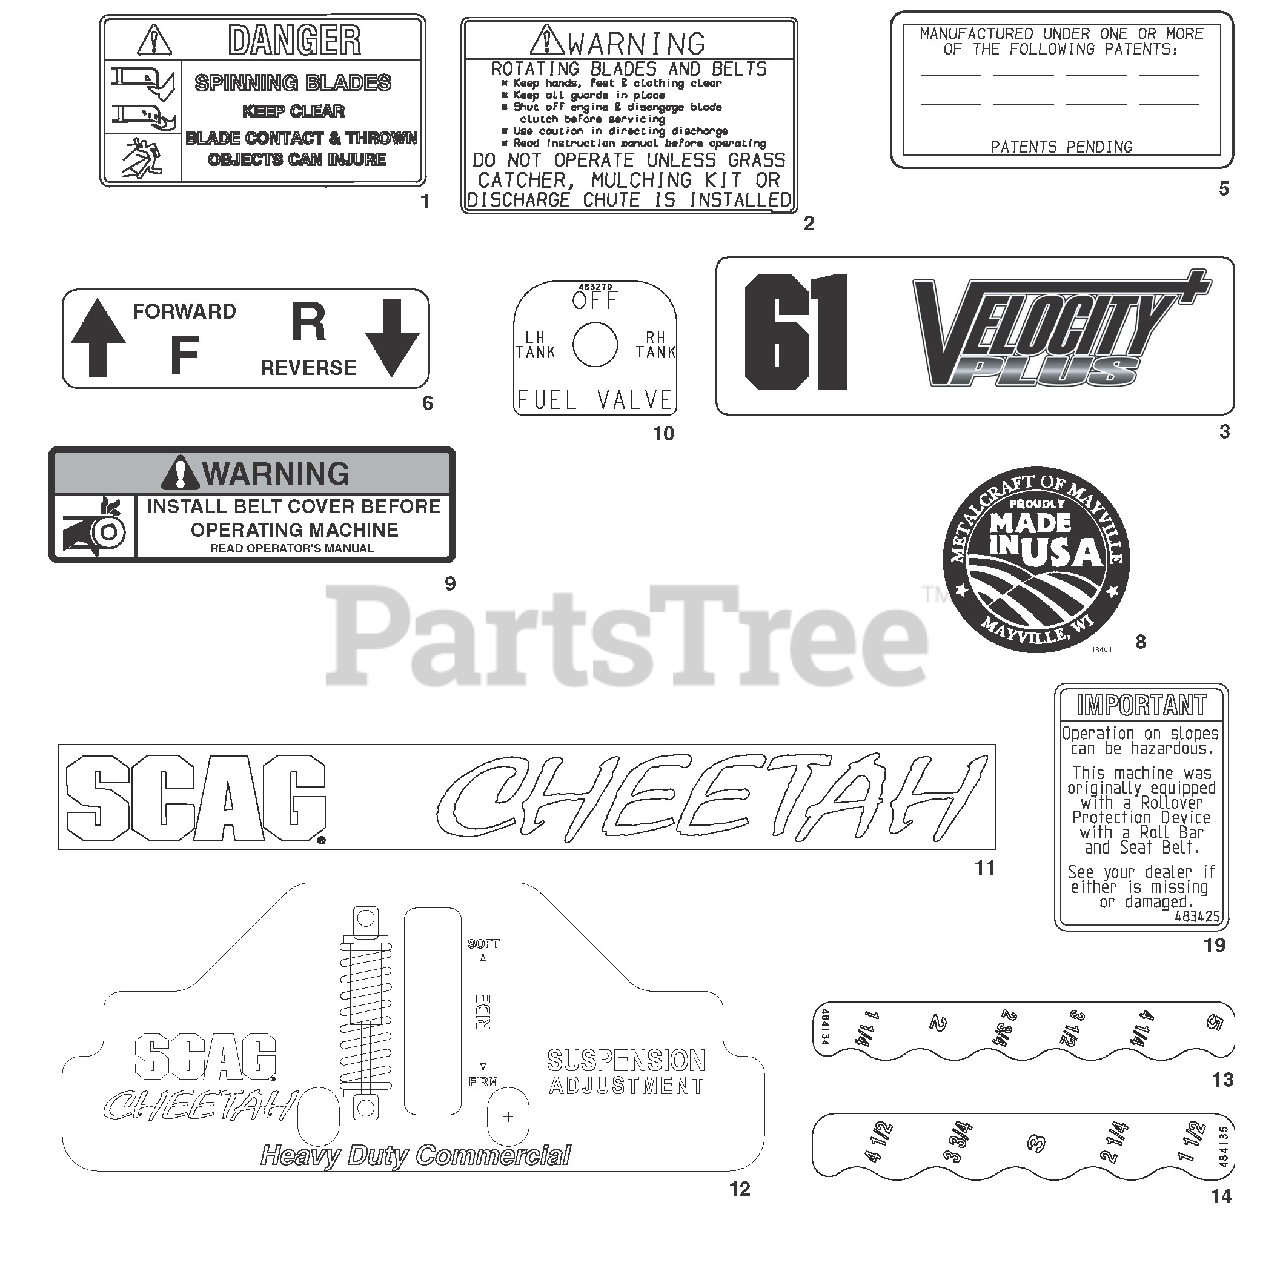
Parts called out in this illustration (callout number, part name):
1	Decal, Spinning Blades
2	Decal, Knives
3	Decal, 61" Velocity Plus
3	Decal, 72" Velocity Plus
5	Decal, Patents
6	Decal, Traction Control
8	Decal, Made in USA
9	Decal, Belt Cover
10	Decal, Fuel Shut Off
11	Decal, Scag Cheetah
12	Decal, Suspension Adjustment
13	Decal, Deck Height - LH
14	Decal, Deck Height - RH
19	Decal, ROPS
